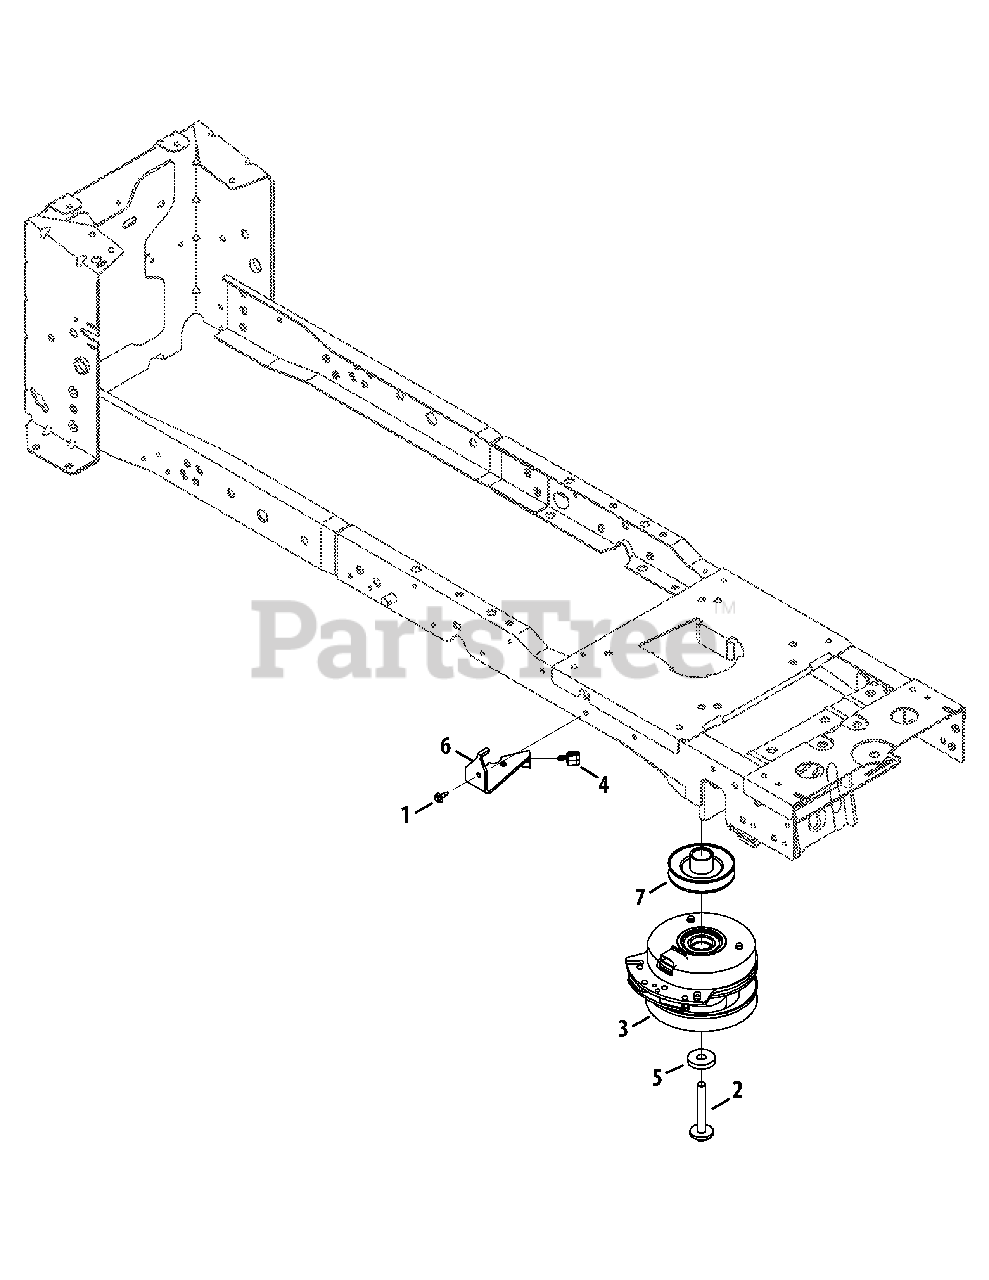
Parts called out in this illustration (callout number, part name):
1	Screw, M6-1 x .625
2	Hex Cap Screw, 7/16-20 x 3.50
3	Clutch, Electric PTO
4	Grommit
5	Flat Washer, .450 x 1.375 x .250
6	Clutch Bracket
7	Engine Pulley
